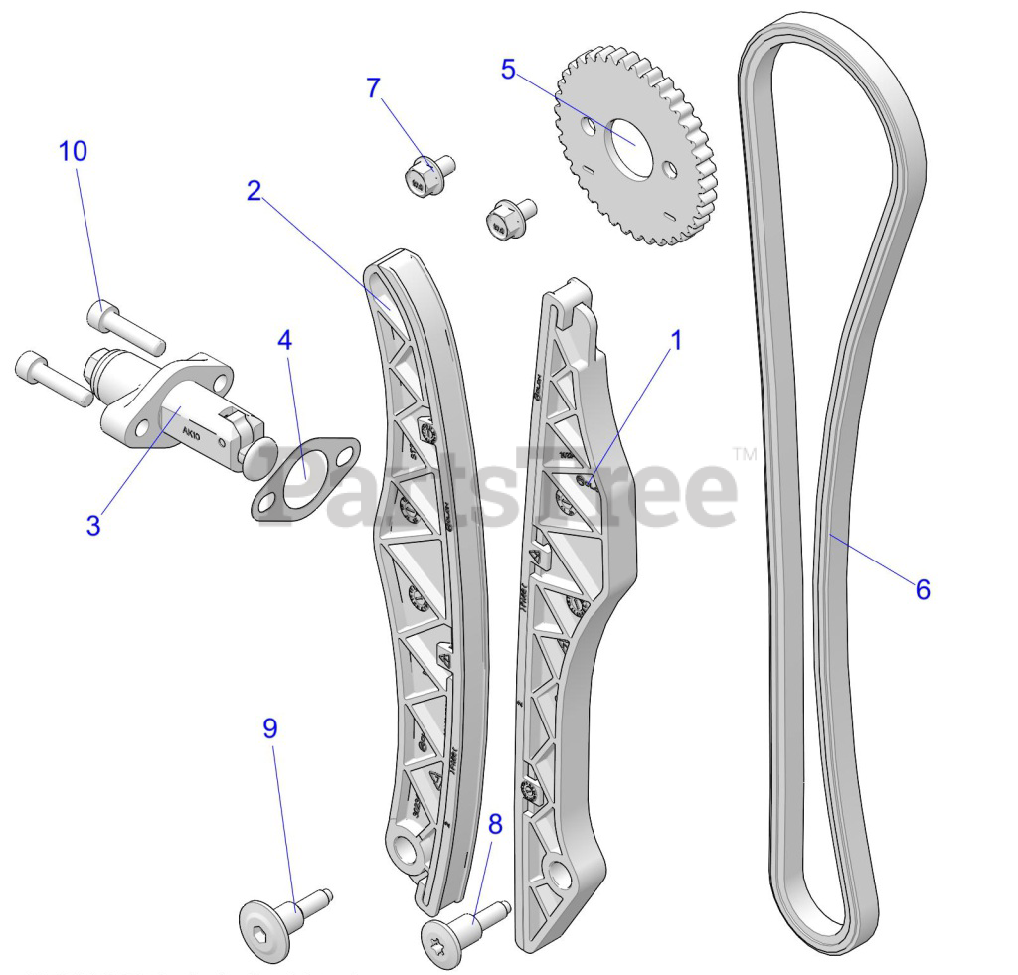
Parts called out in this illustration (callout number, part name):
1	GUIDE-CAM CHAIN- FIXED- SOHC
2	GUIDE-CAM CHAIN-TENSIONER-SOHC
3	TENSIONER-RATCHETING-MECH
4	GASKET-TENSIONER
5	SPROCKET-CAM- DRIVEN- SOHC
6	CHAIN-CAMSHAFT
7	SCR-HXFL-M6X1.0X10 10.9
8	BOLT-SHLDR-M6X12X15
10	SCR-SH-M6X1.0X25 10.9 ZPC D204
